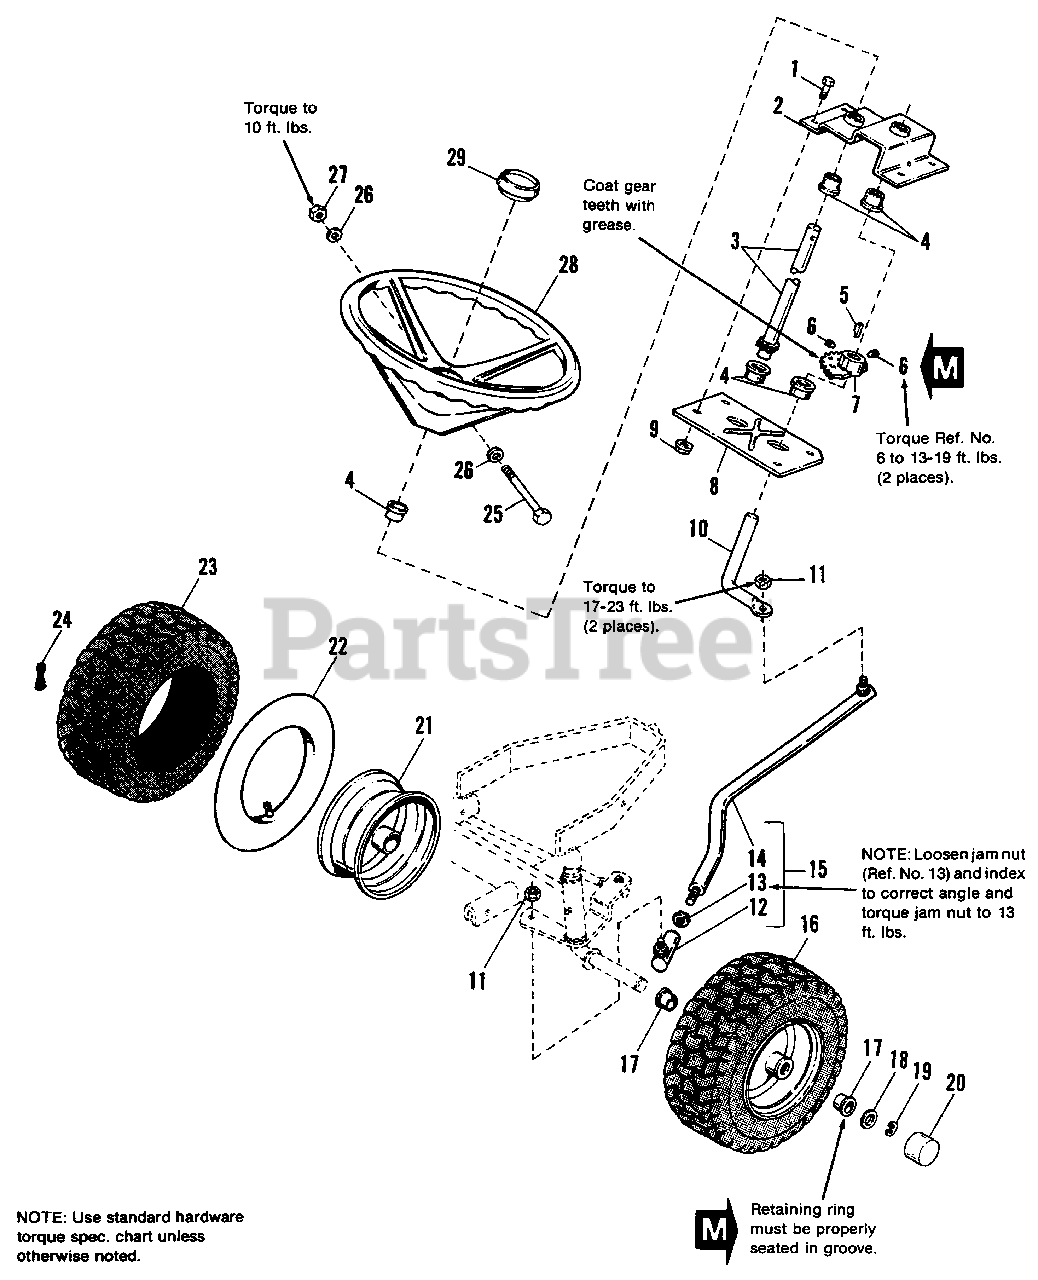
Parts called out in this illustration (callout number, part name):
1	CAPSCREW, Hex Hd., 5/16-18 x 3/4
2	PLATE, Steering
3	SHAFT ASSY., Steering
6	SETSCREW, 5/16-18 x 1/2
7	GEAR, Steering
8	PLATE, Base, Steering
9	NUT, Hex-Flange, 2 Way Lock 5/16-18
10	ROD, Steering
11	NUT, Special 3/8-24
12	BALL JOINT ASSY.
13	NUT, Jam 3/8-24
15	LINK ASSY., Drag (Incl. Ref. Nos. 12, 13 & 14)
16	WHEEL & TIRE ASSY.
19	KLIPRING, External 3/4
20	CAP, Hub, Threaded
21	WHEEL, (Incl. Qty. 2 of Ref. No. 17)
22	TUBE 4.00/3.50-6 (See Note Below)
23	TIRE, 15 x 6.00-6 (Carlisle)
24	VALVE STEM & CAP
25	BOLT, Hex 5/16-18 x 3-1/2
26	WASHER, Plain 5/16
27	NUT, Lock 5/16-18
28	WHEEL, Steering
29	CAP, Steering Wheel
